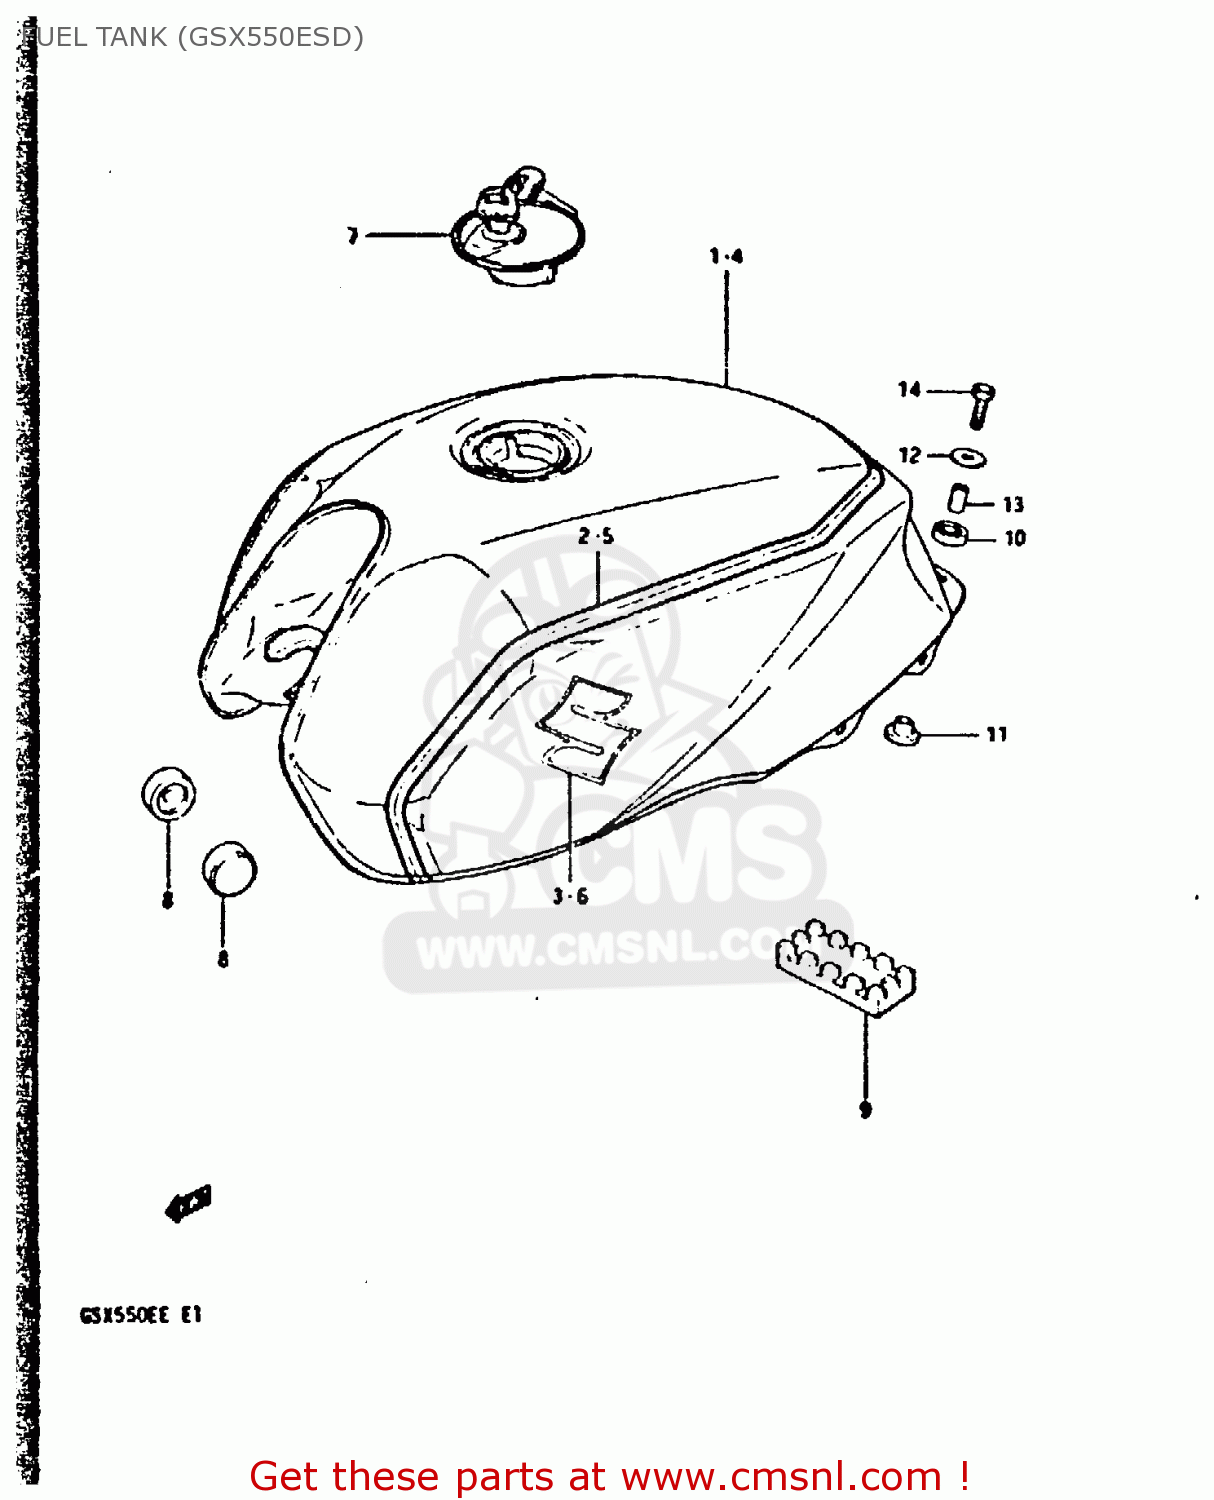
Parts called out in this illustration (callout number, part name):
1	TANK, FUEL
2	TAPE SET,FUEL TANK
3	EMBLEM
4	TANK ASSY, FUEL
5	TAPE SET,FUEL TANK
6	EMBLEM
7	CAP SET,FUEL TANK
8	CUSHION
9	CUSHION,FUEL TANK
10	CUSHION
11	CUSHION
12	WASHER (6.5X24X1.6)
13	SPACER (6.4X9X20)
14	BOLT
